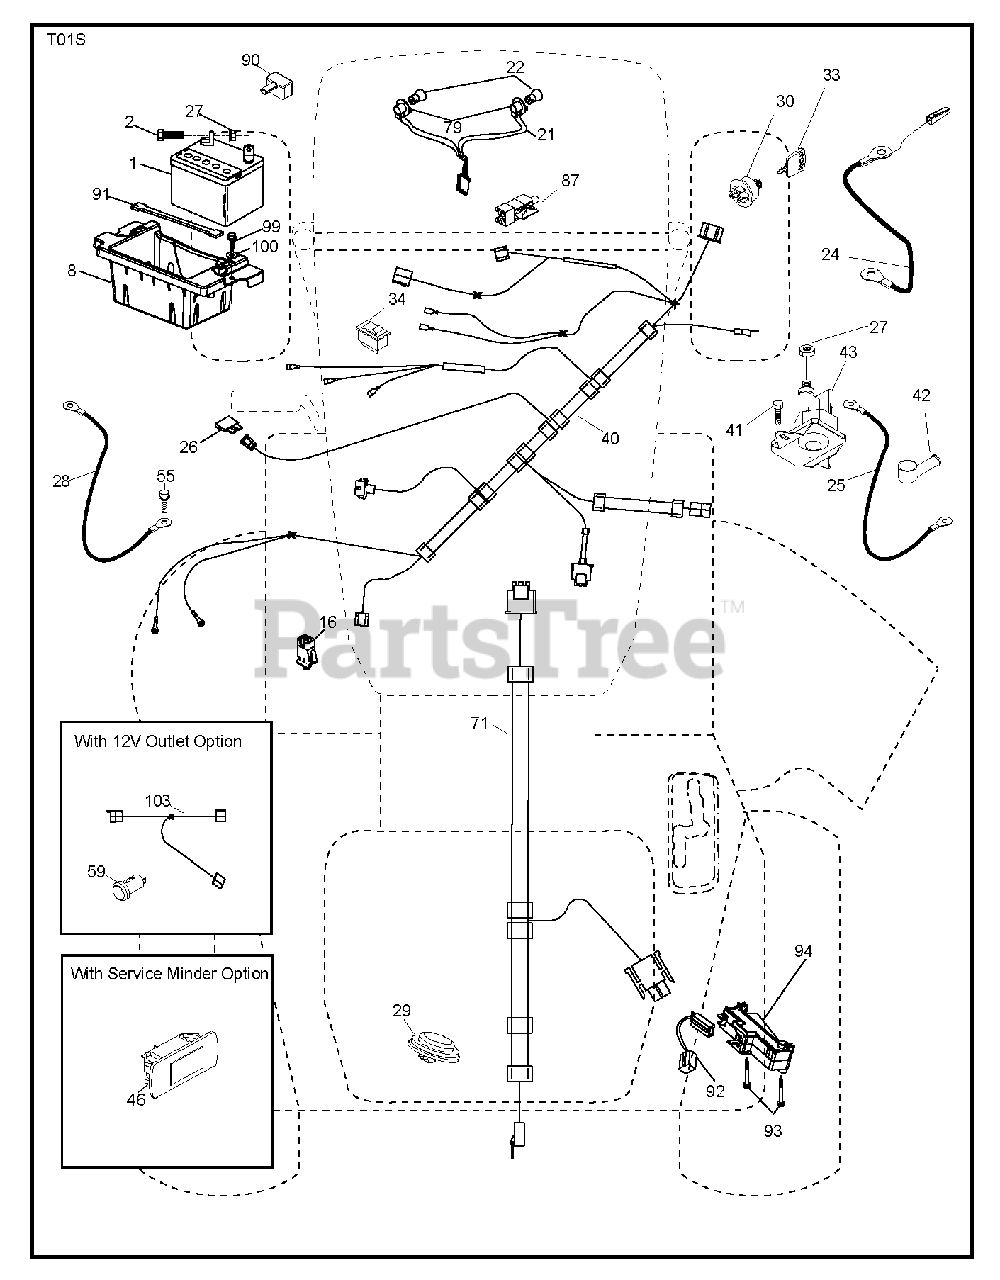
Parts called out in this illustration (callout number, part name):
1	REPL BY 532 12 38-99
2	BOLT.HEX.1/4.X.3/4.DICHROMATE
8	BOX.BATTERY.MOUNT.FRONT.LT
16	SWITCH INTERLOOK PUSH-IN
21	HARNESS ASSY LIGHT
22	LIGHTBULB
24	CABLE.BATT.POS.WIRE.TG.DA SOL
25	CABLE.STARTER.6GA.BL/RED.14.
26	FUSE 20AMP
27	NUT
28	CABLE GROUND 6 GA 21" 90T BLK
29	SWITCH.SEAT.DELTA.OPC.
30	SWITCH.IGN.DELTA.W.LGH.ROS
33	KEY.CHAIN.BLISTER.PACK.GEN.INT
34	SWITCH LT
40	HARNESS IGN. DASH
41	SCREW
42	TERMINAL COVER
43	SOLENOID.W/BRASS.PLUNGER
46	GUAGE.SRVCMNDR.HRMTR.
55	SCREW 5/16"
71	HARNESS-CHASSIS SUB
79	BULB HOLDER ASM.
87	SWITCH.INTRLCK.CLUTCH.
90	COVER.TERMINAL.BATTERY
91	STRAP.BATTERY.MOUNT.FRONT
92	HARNESS.PIGTAIL.CONSLE
93	SCREW.PLASTITE
94	MODULE.REVERSE.ROS
99	SCREW HEXWSHR 1/4-20X3/4
